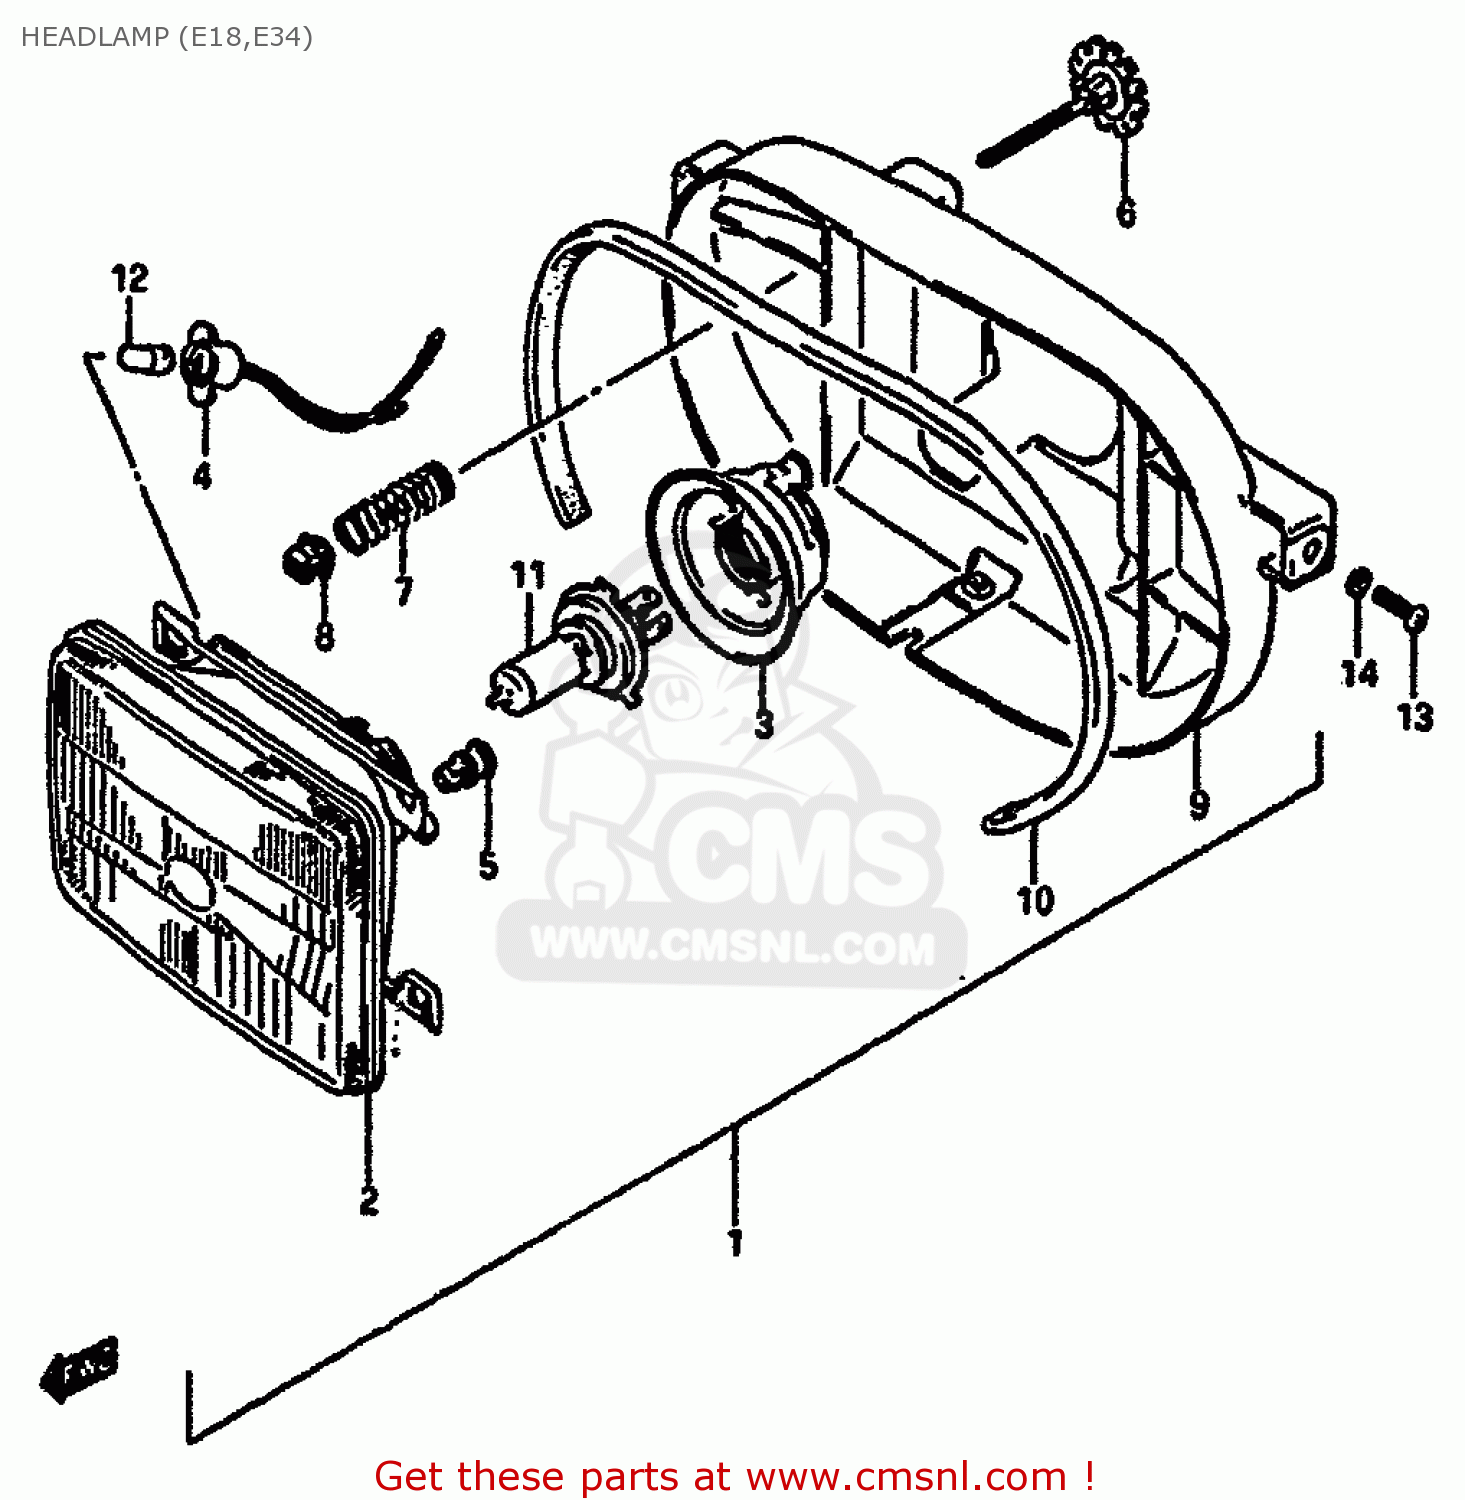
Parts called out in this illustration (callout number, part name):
1	HEADLAMP ASSY
2	UNIT
3	COVER,SOCKET
4	SOCKET
5	SCREW,SPHERICAL
6	SCREW,ADJUSTER
7	SPRING
8	NUT
9	HOUSING
10	GASKET (NAS)
11	BULB(12V60/55W,H4)
12	BULB(12V4W)
13	SCREW
14	WASHER,LOCK
